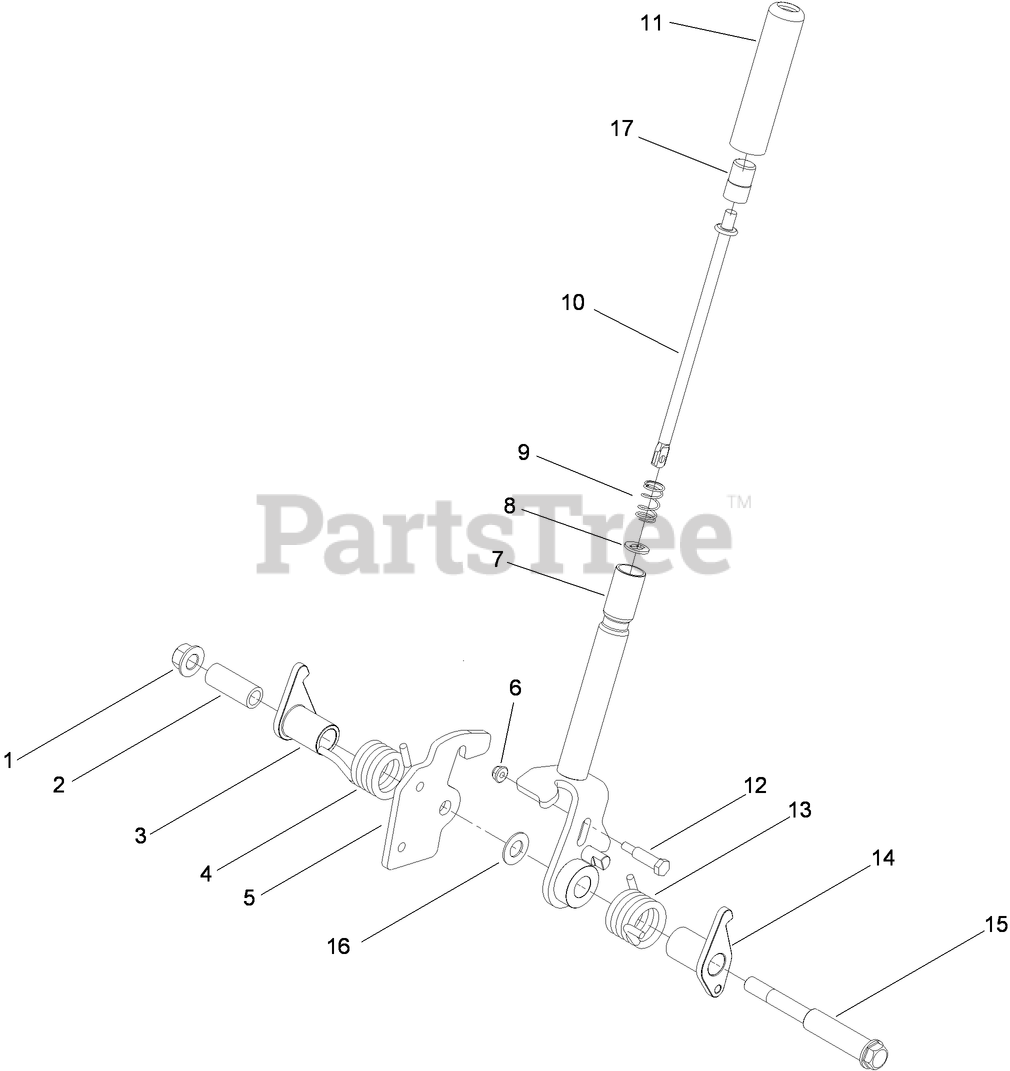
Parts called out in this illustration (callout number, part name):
1	NUT-LOCK
2	SPACER
3	ARM-BRAKE, LH
4	SPRING-TORSION, RH
5	PLATE-LATCH
6	NUT-HF
7	BRAKE HANDLE ASM
8	WASHER-SPECIAL
9	SPRING-COMPRESSION
10	ROD-RELEASE, BRAKE
12	BOLT-SHOULDER
13	SPRING-TORSION, LH
14	ARM-BRAKE, RH
15	BOLT-SHOULDER
16	WASHER-FLAT
